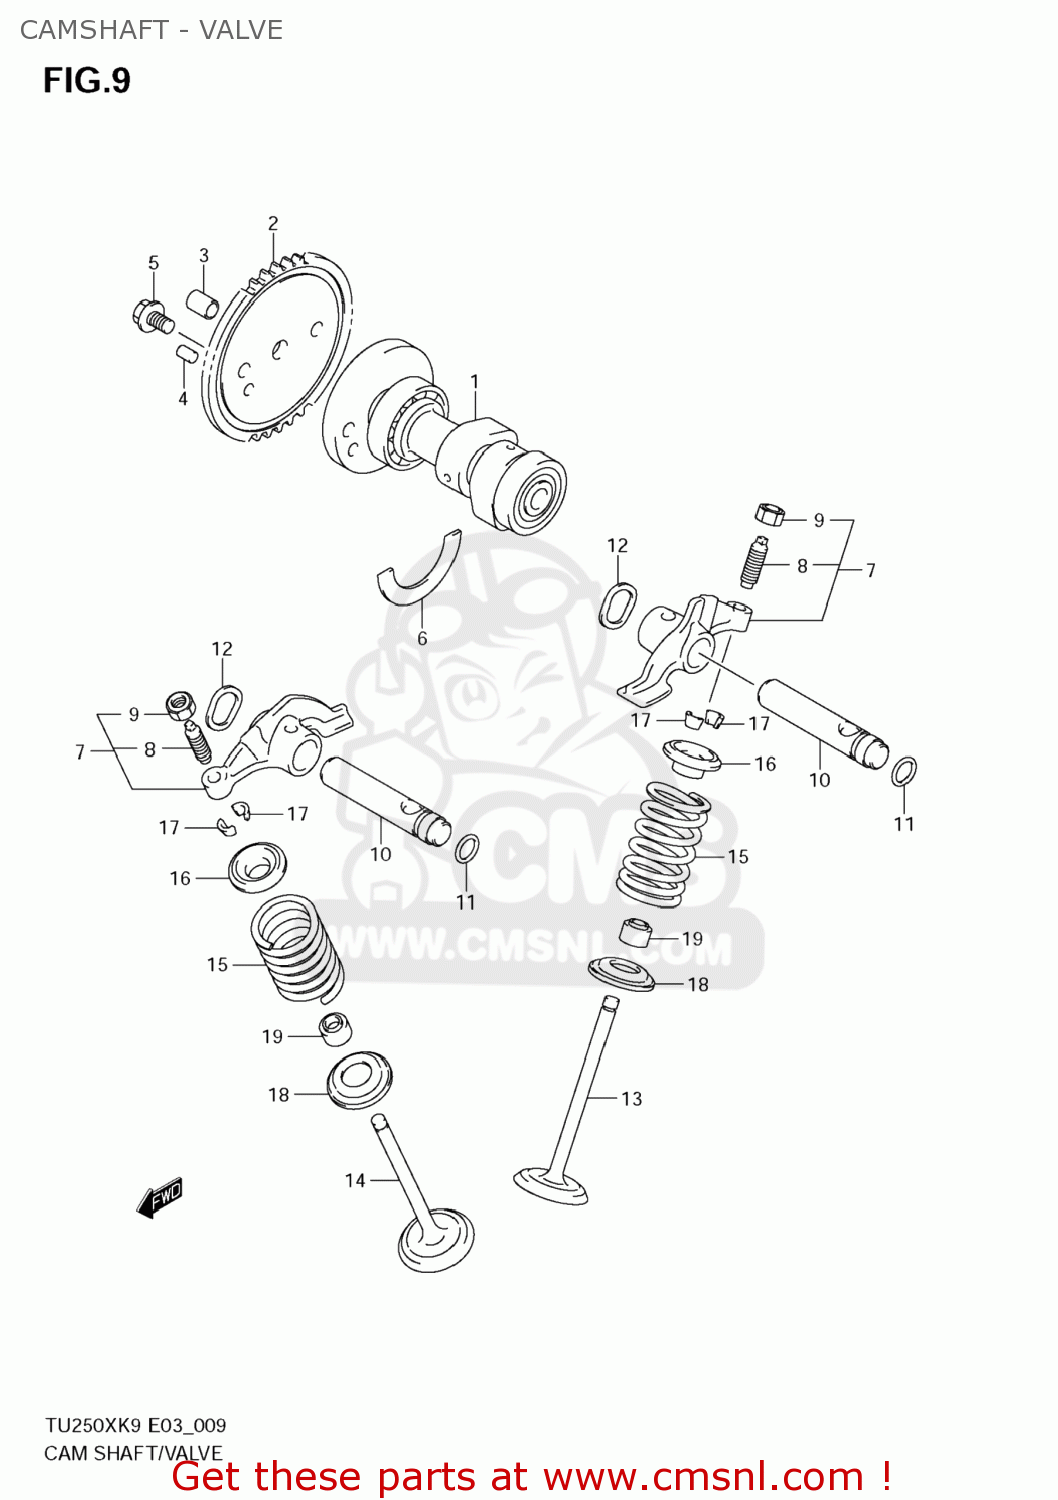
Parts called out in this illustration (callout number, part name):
1	CAMSHAFT
2	SPROCKET,CAMSHAFT
3	PIN(6.2X8X11)
4	PIN(5X8)
5	BOLT
6	C RING
7	ARM,VALVE ROCKER
8	SCREW,TAPPET ADJUSTING
9	NUT,ADJUSTING SCREW
10	SHAFT,VALVE ROCKER ARM
11	O RING(D:1.9,ID:8.6)
12	WASHER
13	VALVE,INTAKE
14	VALVE,EXHAUST
15	SPRING,VALVE
16	RETAINER,VALVE SPRING
17	COTTER,VALVE
18	SEAT,VALVE SPRING
19	SEAL,OIL(5.5X11X8.2)
